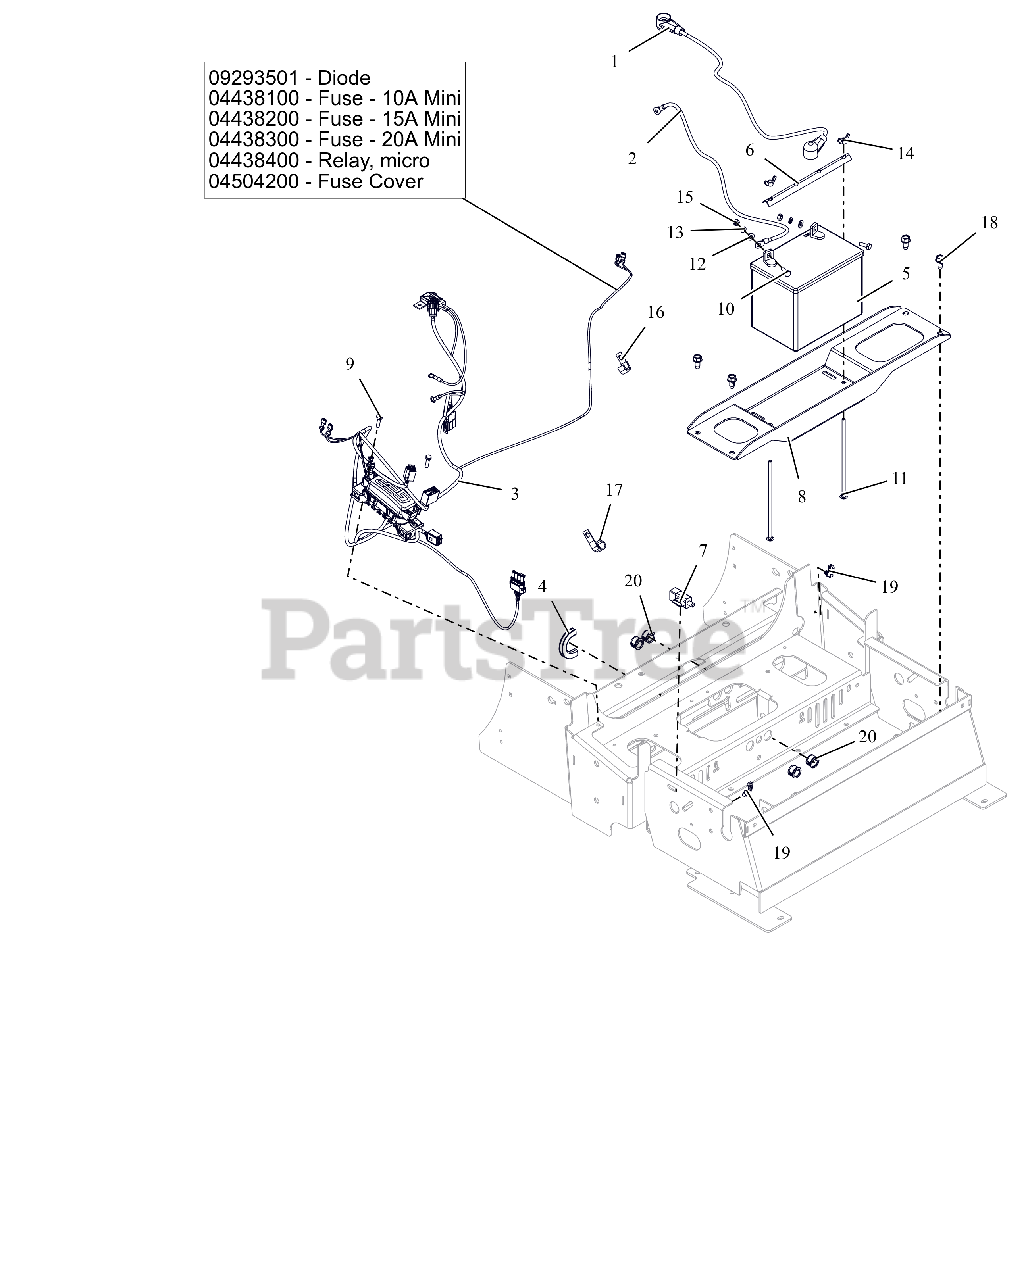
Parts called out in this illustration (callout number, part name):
1	CABLE - POS BATT W/BOOTS 6X35
2	CABLE-NEGATIVE BATTERY 35.00"
3	HARNESS, PT200/400 EFI WIRING
3	DIODE, CONNECTOR SHELL
3	FUSE,10 AMP MINI-ATC
3	FUSE,15 AMP MINI-ATC
3	FUSE,20 AMP MINI ATC
3	RELAY,MICRO5 TERML W/RESISTOR
3	COVER, HARNESS FUSE/RELAY MOD
4	STRIP, COWL
5	BATTERY, 300 CCA 10U1L
6	HOLD DOWN
7	SWITCH, SNAP IN - N.O./N.O.
8	PT200/400 BATTERY TRAY - RED
9	BLT, HEX M6-1.0 X 25 G8.8 ZCC
10	BLT, HEX .25-20X.75 G5 ZCC
11	BTL,RHSN .250-20 X 7.5 G5 ZCC
12	WSHR,FLT .281X.625X.065 ZCC
13	WSHR,LK-REG .250X.062 ZCC
14	NUT, LK-WING .25-20 ZCC
15	NUT-STD .250-20 G2 ZCC
18	SCR,TAP .375-16X.75 HWH TR ZCC
19	CABLE TIE W/ TREE (.25 HOLE)
20	BUSH, PANEL SNAP .687X.875X.56
